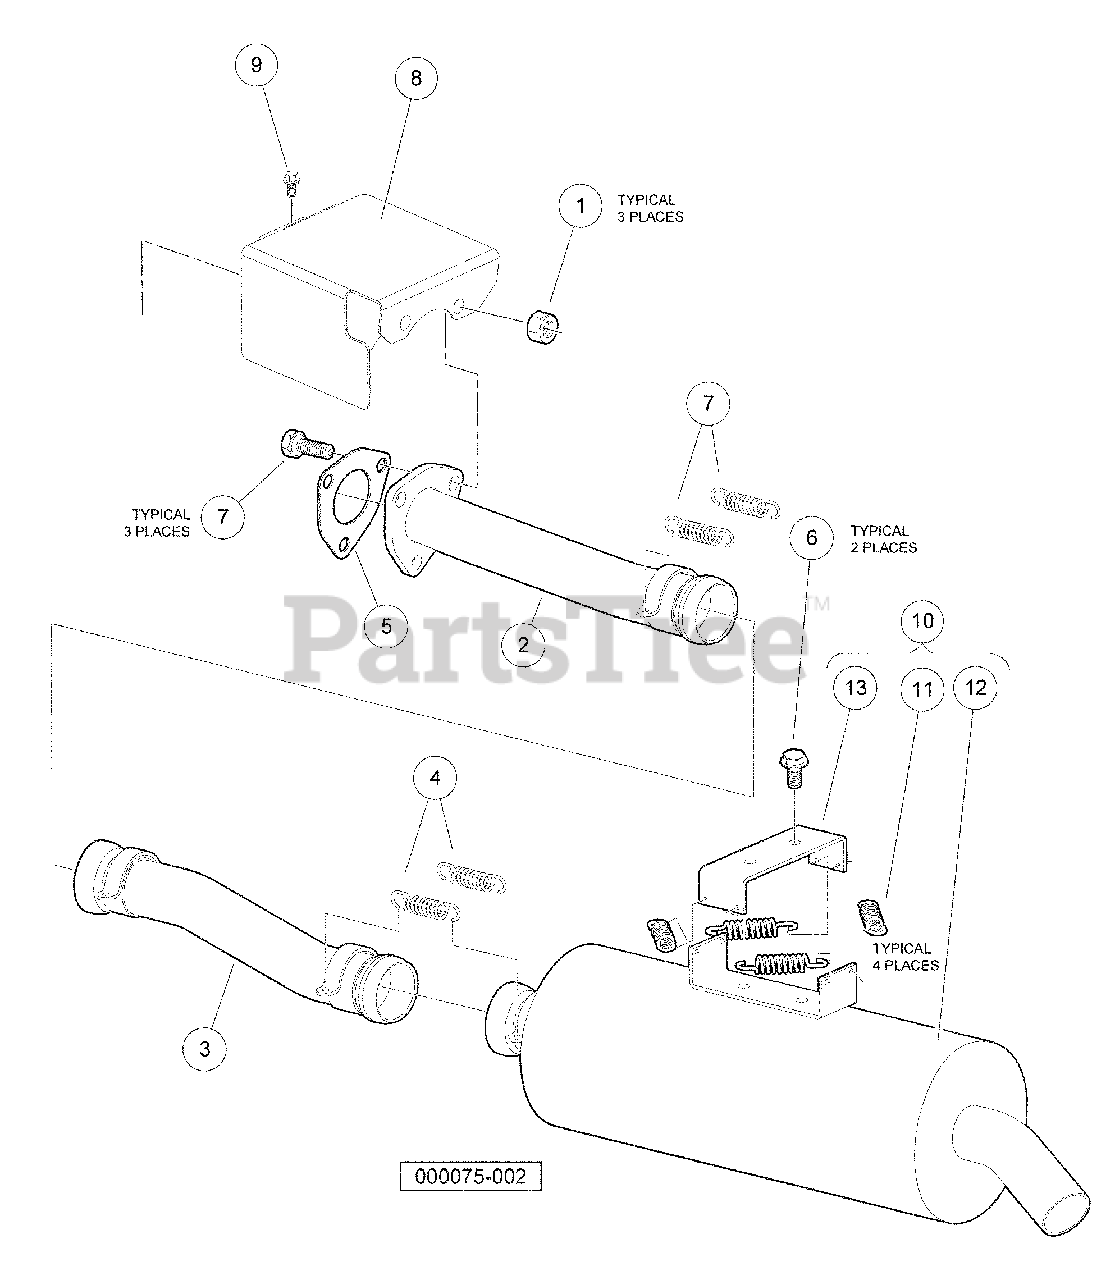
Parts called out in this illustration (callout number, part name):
1	Nut,m8,all Metal Lock
2	Pipe, Exhaust Diesel Main
3	Pipe, Exhaust Intermediate
4	Spring, Exhaust
5	Gasket, Exhaust Diesel
6	Bolt Flanged Head, M8 X1.25x 16 with Loctite
7	Bolt, M8 X 1.25 X 40 with Loctite
8	Shield, Diesel Exhaust
9	Bolt, D722, Exhst Manfld Cover
10	Asm, Muffler, AWD Homologation
11	Spring, Exhaust
12	Muffler
13	Bracket, Muffler
